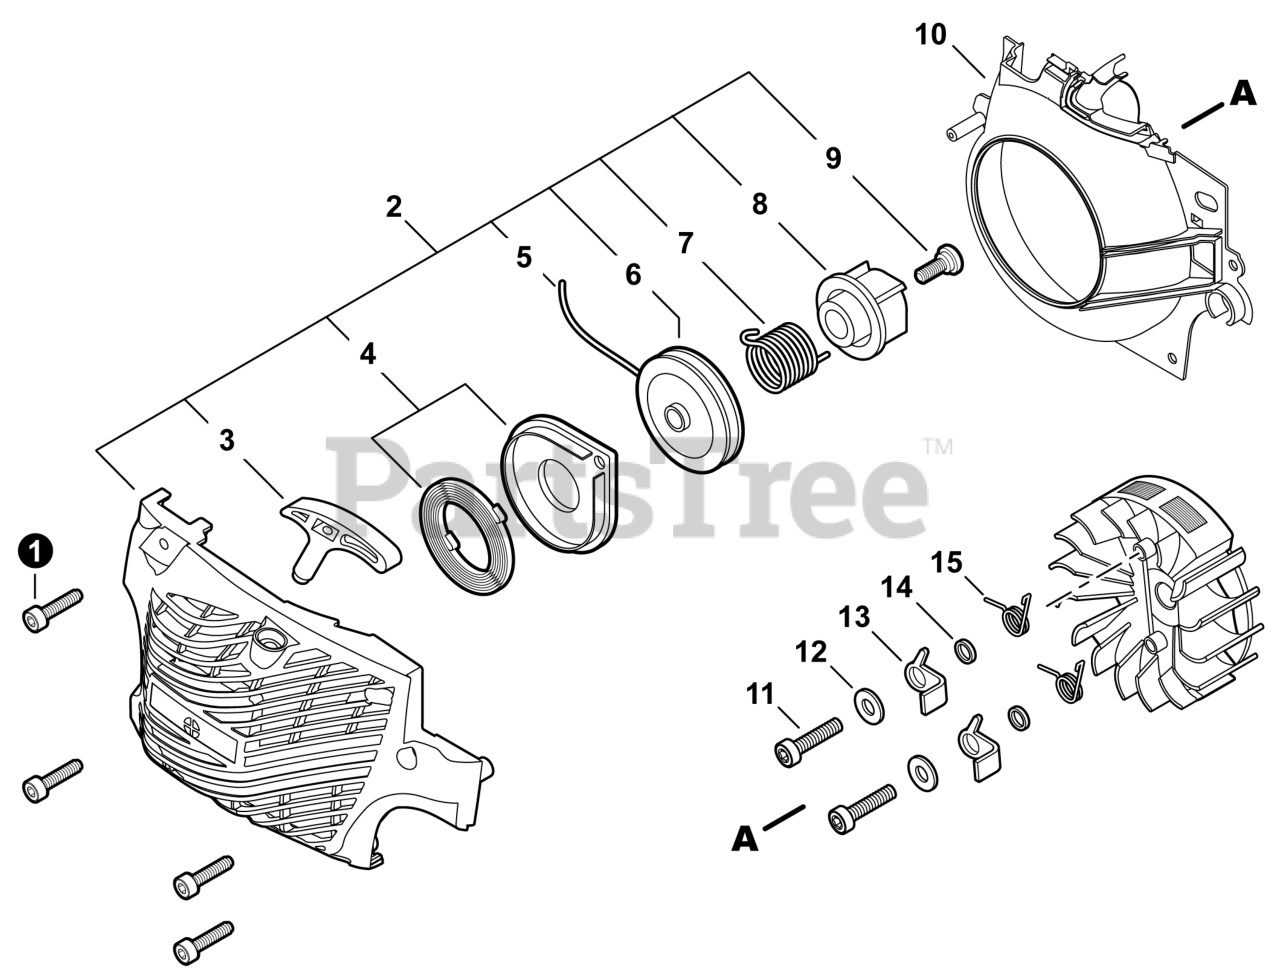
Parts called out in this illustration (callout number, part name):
1	BOLT, TORX 5x20
2	STARTER ASSY, RECOIL
3	GRIP, STARTER
4	SPRING KIT, REWIND
5	ROPE, STARTER 3.5x900
6	REEL, ROPE
7	SPRING, TORSION
8	PAWL CATCHER
9	SCREW
10	COVER, FAN
11	BOLT 5x14
12	WASHER 5.5x12x0.8
14	SPACER 5.2x8x2.1
15	SPRING, TORSION
